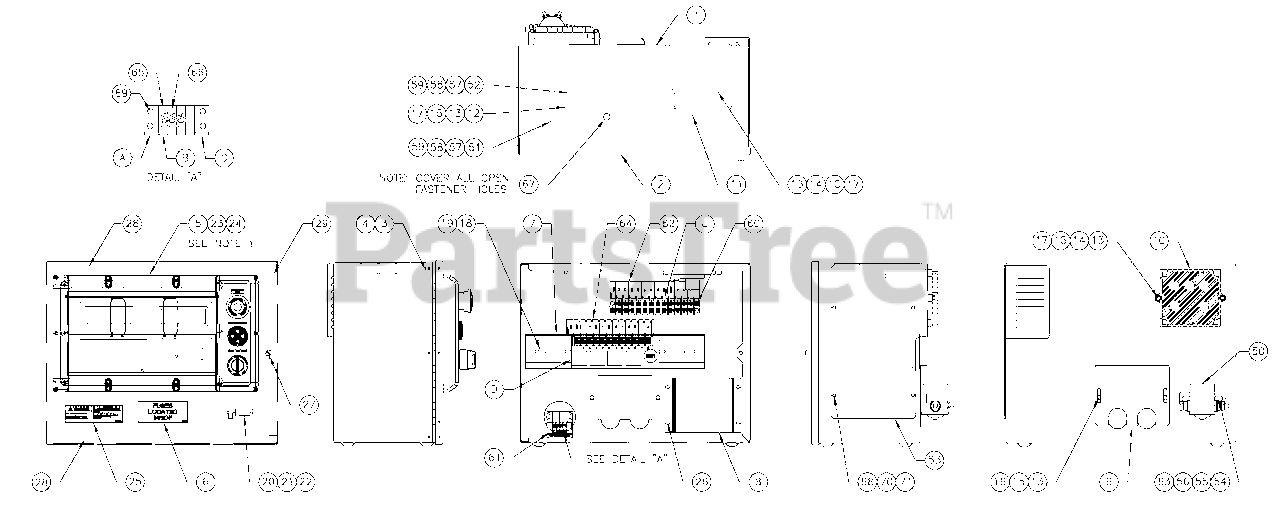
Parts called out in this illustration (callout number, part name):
1	ENCL H/G CONTROL PANEL
2	COVER CONTROL PANEL
3	HINGE CONTINUOUS H PANEL
4	RIVET POP .125 X .275 SS
5	ASSY PROGRAMMED H-100
6	DECAL FUSES LOCAT ED INSIDE
7	RAIL SNAPTRACK PCB HOLDER BULK (12"LG)
8	ASSY PCB 2AMP 12V UL BATT CHGR
9	PLATE HARNESS CLAMP
10	ASSY PCB PWR AVR W/AMP HEADER
11	ASSY PCB BOSCH GOV DRIVER
12	DIO BR IDGE 25A 600V
13	WASHER LOCK M5
14	SCREW PPHM M5-0.8 X 30 SS
15	WASHER FLAT M5
16	SCREW HHPM M5-0.8 X 12
17	NUT HEX M5-0.8 G8 YEL CHR
18	WASHER FLAT M4
19	SCREW PHTT M4-0.7 X 10 ZYC
20	CONN DUST CAP W/CHAIN DB9
21	WASHER FLAT M3.5
22	SCREW PHTT M3.5-0.6 X 10
23	SCREW PPHM M4-0.7 X 8 BLX OX
24	WASHER LOCK #8-M4
25	DECAL WRN B ATT CHRG 12/24V BI
26	SCREW PHTT M4-0.7 X 12 ZYC
27	M5-0.8 CAPTIVE PANEL KNLD HD
28	SEAL COVER 3.18 X 12.7 X 382
29	SEAL COVER 3.18 X 12.7 X 283
50	RELAY CONTACTOR 12VDC
51	DPE B REAKER SEE DRAWING 0F9280
52	BOOST RESISTOR SEE DRAWING 0F9280
53	COVER CONTROL PANEL SIDE
54	SCREW HHC 1/4-20 X 3/4 G5
55	WASHER FLAT M6-1/4
56	WASHER LOCK M6-1/4
57	WASHER LOCK M3
58	NUT HEX M3-0.5 G8 YEL CHR
59	WASHER FLAT M3
60	SCREW PHTT #6-32 X 5/8 ZYC
61	DECAL CPL CONTROL PANEL FUSES
62	DECAL CPL 5.4/6.8L TB3
63	NUT HEX 1/4-20 STEEL
64	DECAL CPL 5.4/6.8L RELAY BOARD
65	FUSE ATO TYPE 15 AMP (BLUE)
66	FUSE ATO TYPE 10 AMP (RED)
67	SEAL WEATHER .45"DIA
68	SCREW PPHM M5-0.8 X 12 ZNC
69	SCREW PHTT #6-32 X 3/8 ZYC
70	WASHER FLAT M5
71	WASHER LOCK M5
A	ADPTR RH SIDE WICKMANN 178.6191
B	HOLDER FUSE WICKMANN 178.6150
C	ADPTR LH SIDE WICKMANN 178.6192
D	ASSY PCB G-PANEL RELAY 12VDC
E	BLOCK TERM 20A 12 X 6 X 1100V
